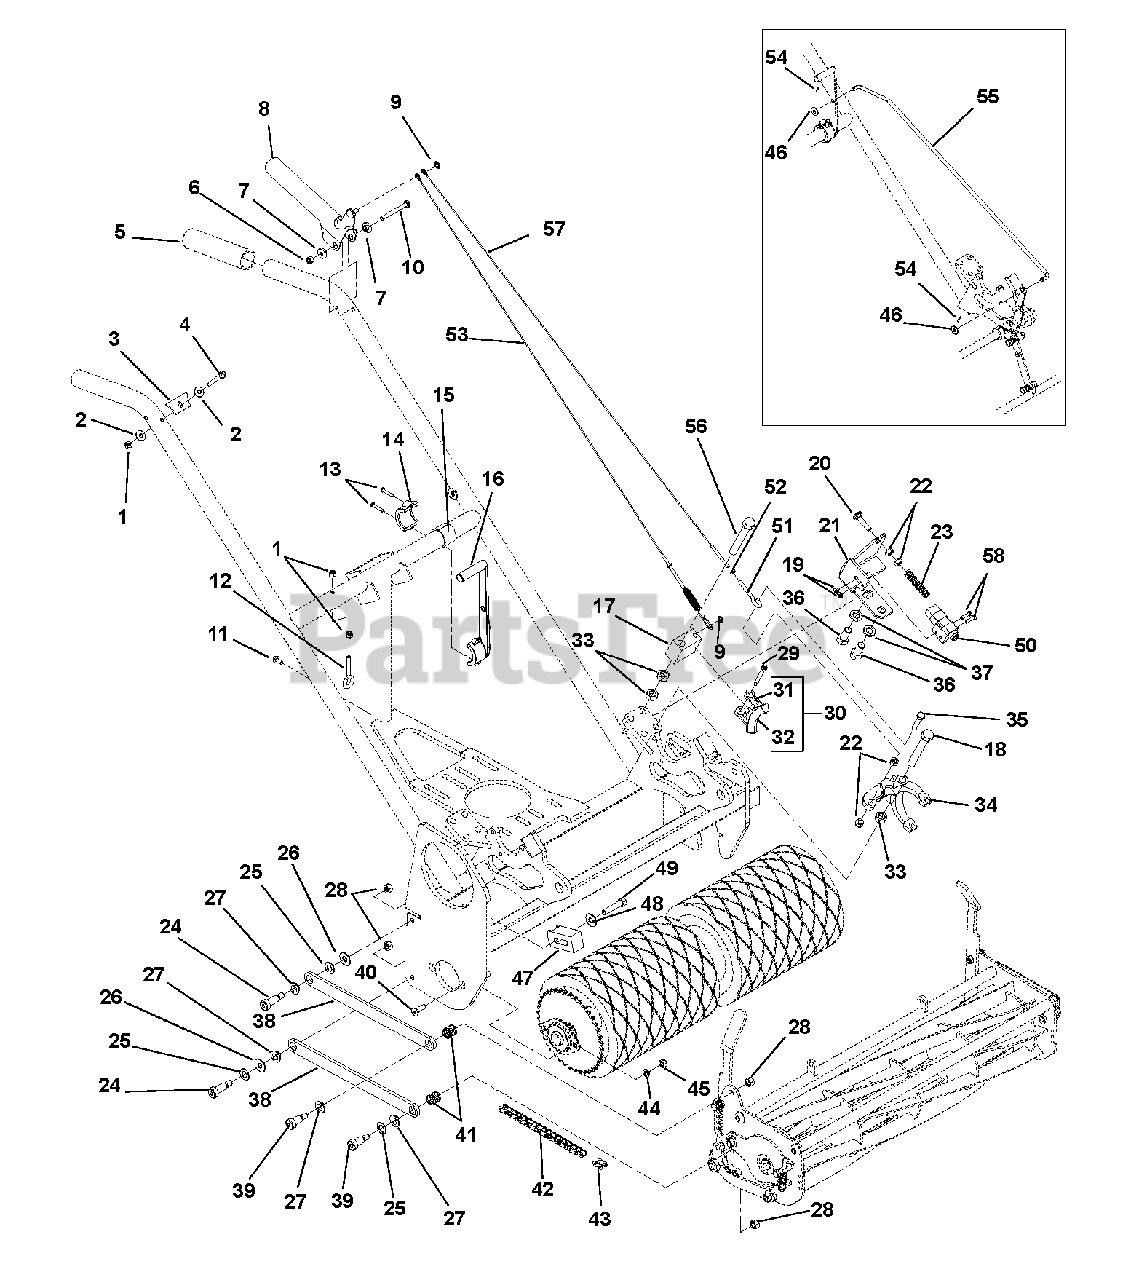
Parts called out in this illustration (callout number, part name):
2	Washer, Flat .25
3	Stop, Handle
4	Screw, Pan Head Slotted .25-20 x 2
6	Nut, Hex .25-20 Nyloc
7	Bushing, Flange
8	Paddle, Right Hand
9	Ring, Retaining .25
10	Cap Screw, Hex Head .25-20 x 2.5
11	Screw, Caster Pin .25-28 Pan Head Slotted Stainless Steel
12	Eyebolt .25-20 x 1.563
13	Screw, Round Head Machine 10-24 x .75
14	Cap, Hand Lever
15	Bushing, Lever
16	Handle, Reel Lift
17	Braking Block, Left Side
18	Cap Screw, Hex Head .50-20 x 3.5
19	Nut, Nylock #10-24
20	Bolt, Carriage .312-18 x 1.5
21	Braking Retainer, Left Hand
22	Nut, Hex .312-18
24	Screw, Shoulder .50 Diameter .38 x 1
25	Washer, Metal Bushing .50 x 18
27	Bushing, Sintered Steel, Oil Impregnated
28	Nut, Hex .375-16
30	Assembly, Brake (Includes Items 31 & 32)
31	Shoe, Brake
32	Pad, Brake
33	Nut, Hex Jam .50-20
34	Lever, Clutch Fork
35	Cap Screw, Hex Head .312-18 x 1.5
36	Cap Screw, Hex Head .50-20 x 1
37	Washer, Lock .50
38	Arm, Reel
39	Bolt, Arm Stainless Steel, .50 Shoulder 18-8
40	Cap Screw, Flat Head Socket .312-18 x 1 Stainless Steel
41	Spring, Reel .750 OD x .090 Wire Diameter x .730 – .750 Free Length
42	Chain, Traction Drive (31" #423)
43	Master Link
44	Washer, Lock .312
45	Nut, Hex .312-10
46	Washer, Flat .312
47	Adjuster, Chain
48	Washer, Flat .375
49	Cap Screw, Hex Head .38-16 x 1.75
50	Switch, Double Pole Plunger
51	Eyebolt .186 10-24 x 3
52	Nut, Hex 10-24
53	Cable Assembly, CL Brake
54	Pin, Cotter
55	Rod, Mower Lift 29-Inch
56	Cap Screw, Hex Head .50-20 x 3
57	Cable Assembly, CL Reel Clutch
58	Screw, Pan Head Phillips 10-20 x .75
